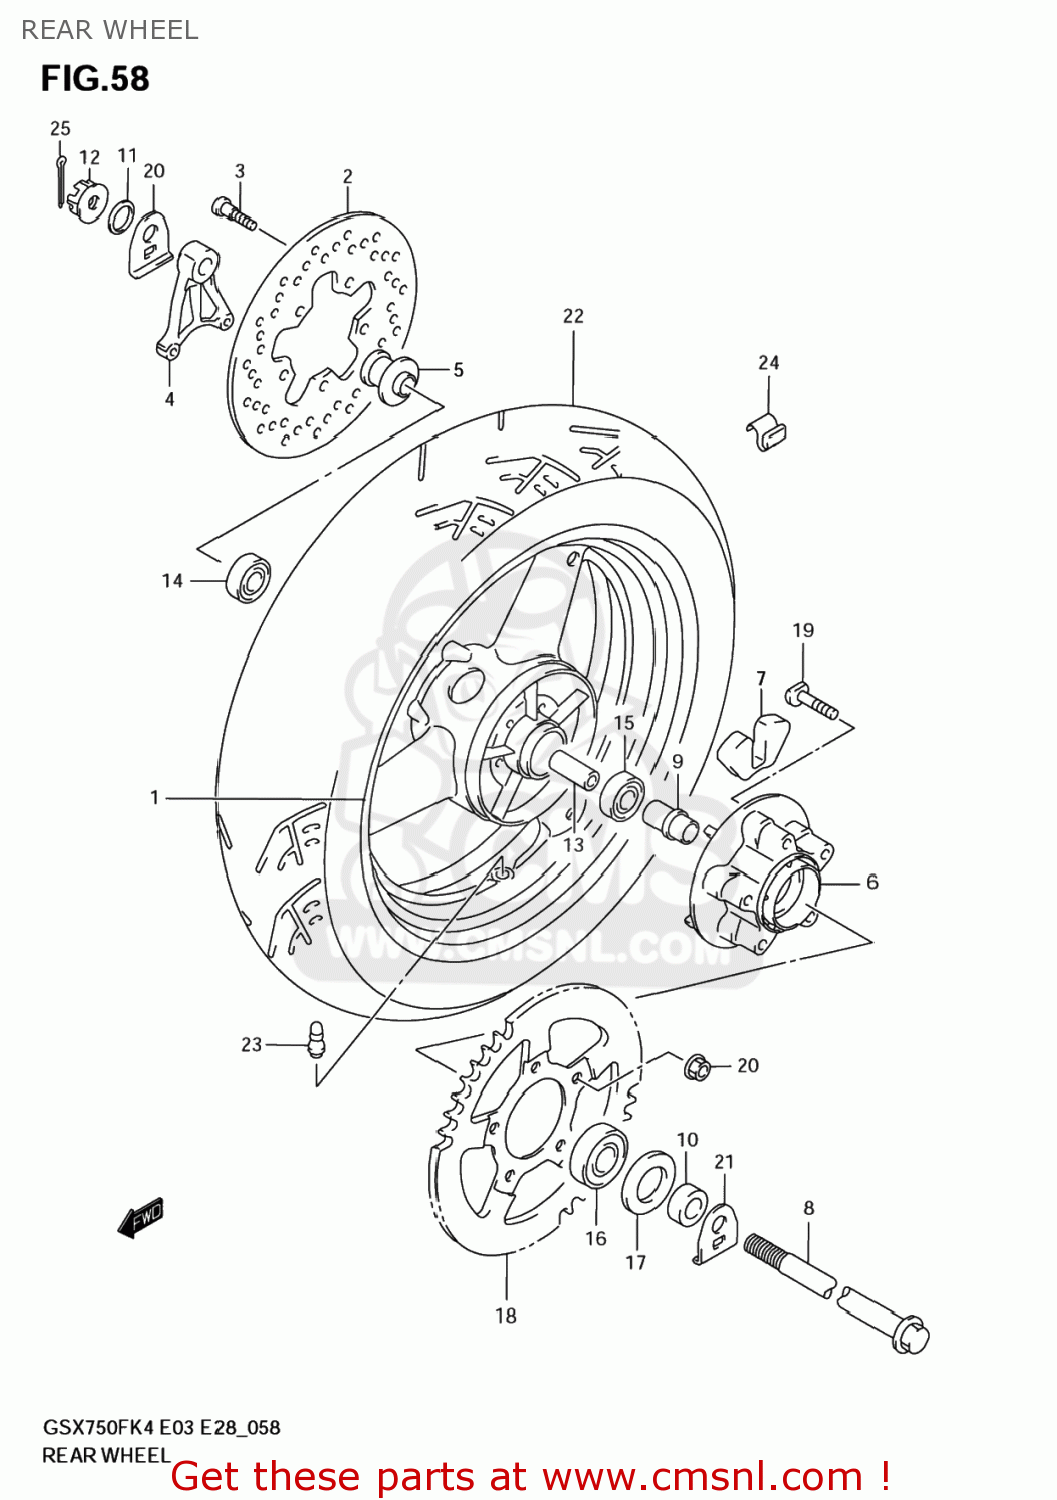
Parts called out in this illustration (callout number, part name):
1	WHEEL,RR(17M/CXMT4.50)
2	DISC,RR BRAKE
3	BOLT 8X33
4	BRACKET,RR CALIPER
5	SPACER,RR AXLE,R
6	DRUM,RR SPROCKET
7	ABSORBER,RR HUB SHOCK
8	AXLE,RR
9	RETAINER,RR SPROCKET DRUM
10	SPACER,RR AXLE,R
11	WASHER(17X30X3.2)
12	NUT
13	SPACER(17.5X25X88)
14	BEARING
15	BEARING
16	BEARING(25X62X17)
17	SEAL,OIL(35X62X8)
18	SPROCKET,RR(NT:45-530)
19	BOLT(10X47)
20	NUT
21	WASHER,CHAIN ADJUSTER
22	TIRE,RR(150/70 ZR17 69W)
23	VALVE ASSY,WHEEL RIM(TR412)
24	BALANCER,WHEEL(10G)
25	PIN,COTTER
